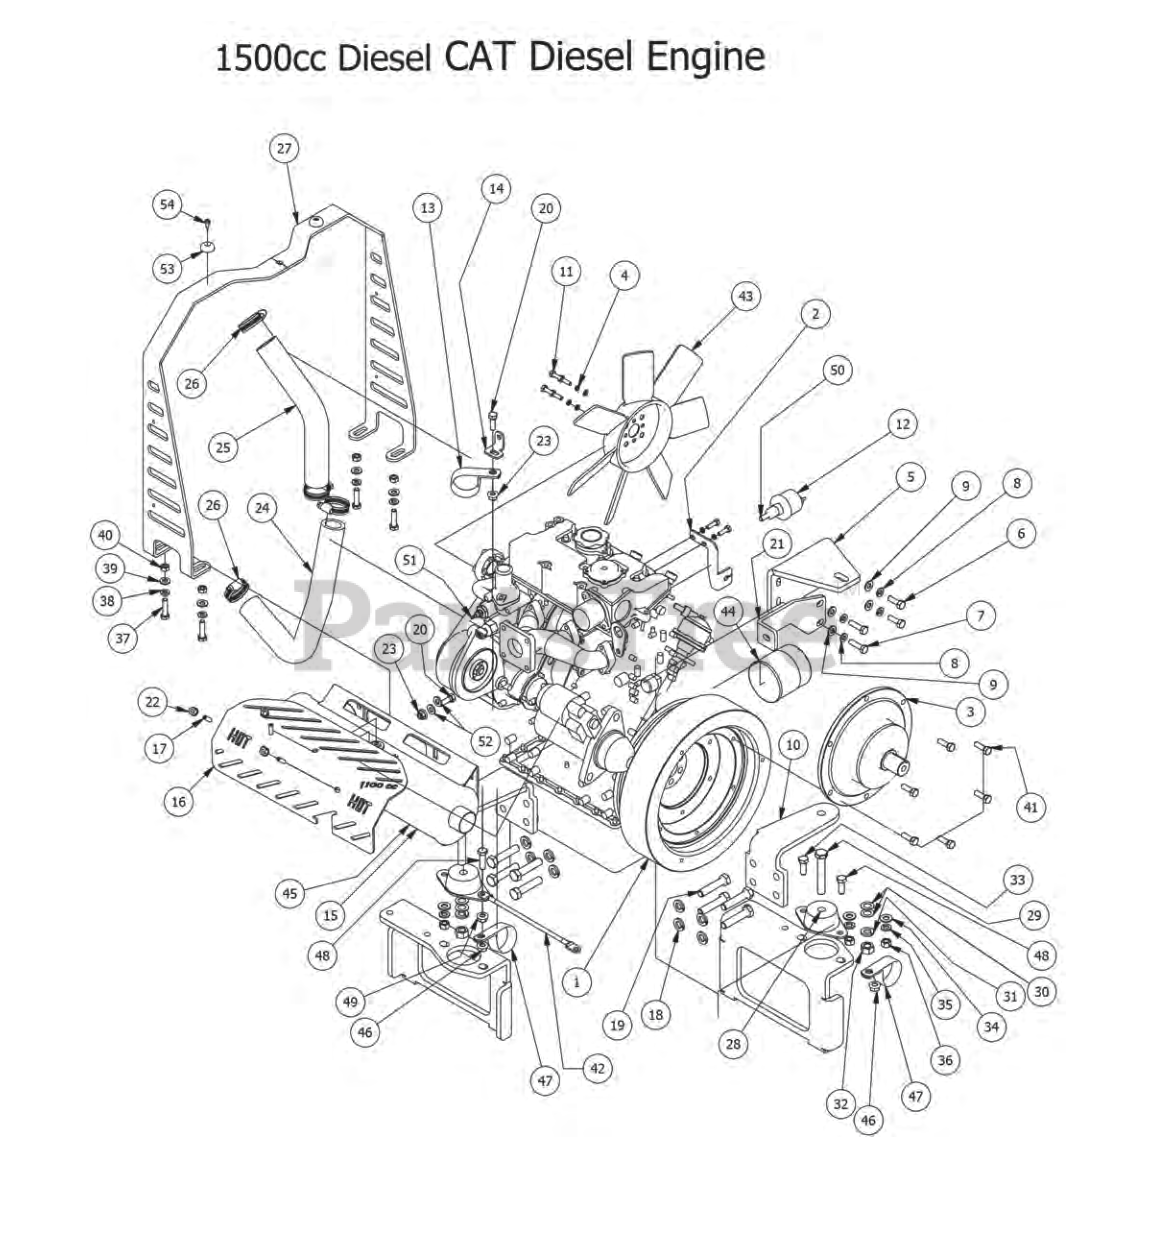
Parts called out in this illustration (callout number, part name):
1	35HP CAT Diesel Engine
2	Diesel Throttle Bracket (4 Tier)
3	Stub Shaft
4	1/4" Lock Washer
5	Air Cleaner Support Diesel
6	M8 x 1.25 x 25mm Hex Head Bolt
7	M8 x 1.25 x 30mm Hex Head Bolt
8	5/16" Lock Washer
9	5/16" Flat Washer
10	Diesel Motor Side Support Right
11	6mm x 20mm Bolt
12	Pressure Sender-2012 Gauge and Up
13	Diesel Clamp 1 3/4" Vinyl
14	Diesel Radiator Hose Clamp Bracket
15	28/35hp Caterpillar Muffler
16	Diesel Muffler Guard (35Hp)
17	1/4" x 3/4" Set Screw
18	1/2" Lock Washer
19	12mm Bolt-Diesel
20	5/16" x 1" Bolt
21	Muffler Brace Diesel
22	1/4-20 Nylon Insert flange Nut
23	5/16" Flange Nut
24	Bottom Radiator Hose for Diesel
25	Top Radiator Hose for Diesel
26	1 1/8" Hose Clamp
27	Hood Holder Diesel
28	Rubber Isolator
29	1/2" x 3" Hex Bolt
30	1/2" Brass Washer
31	1/2" Lock Washer
32	1/2" Hex Nut
33	3/8" x 1" Hex Bolt
34	3/8" Flat Washer
35	3/8" Lock Washer
36	3/8" Hex Nut
37	5/16" x 1 1/4" Hex Bolt
38	5/16" Lock Washer
39	5/16" Flat Washer
41	5/16-18 x 1 Button Head Bolt
42	Starter to Chassis Cable - Diesel-35 Hp
43	Engine Fan- Diesel
44	CAT Oil Filter
45	Diesel Side Motor Mount Left
46	3/8 Nylock Jam Nut 1/2 Nut
47	Diesel Clamp 1 3/4" Vinyl
48	3/8" x 1 1/2" Hex Bolt
49	3/8" Flange Nut
50	Brass Washer for Weld-on Hinge
51	Temperature Sender-2012 Gauge
52	1/4 USS Flat Washer Zinc
53	Button Bumper
54	#10 x 1/2" Self Taping Screw
